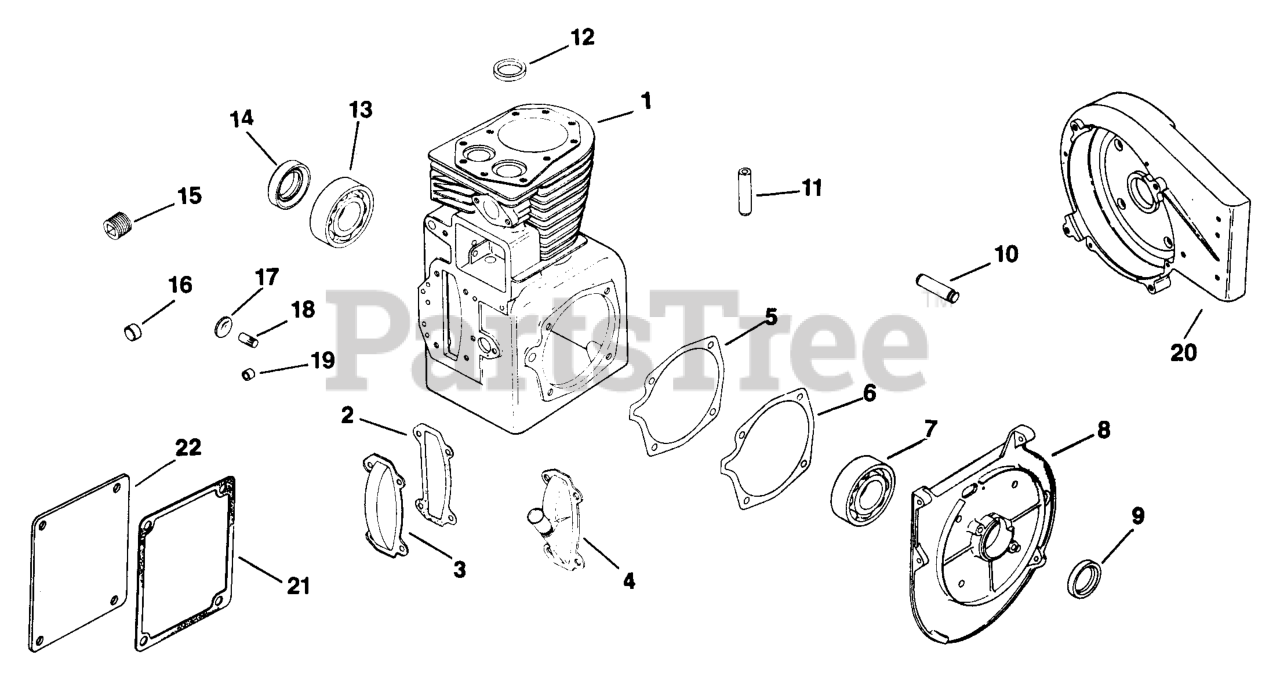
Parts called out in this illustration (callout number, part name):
1	Cylinder Block
2	GASKET, CAMSHAFT COVER
3	COVER, CAMSHAFT - DISCONTINUED
5	GASKET, BEARING PLATE
6	GASKET, BEARING PLATE
7	BEARING, BALL
9	SEAL, FRONT OIL
11	GUIDE, VALVE - DISCONTINUED
13	BEARING, BALL
14	SEAL, REAR OIL
17	PLUG, WELCH EXPANSION
18	SHAFT, GOVERNOR GEAR
19	BEARING
X-132-6-S	SCREW, SEMS 1/4-20-1/2"
